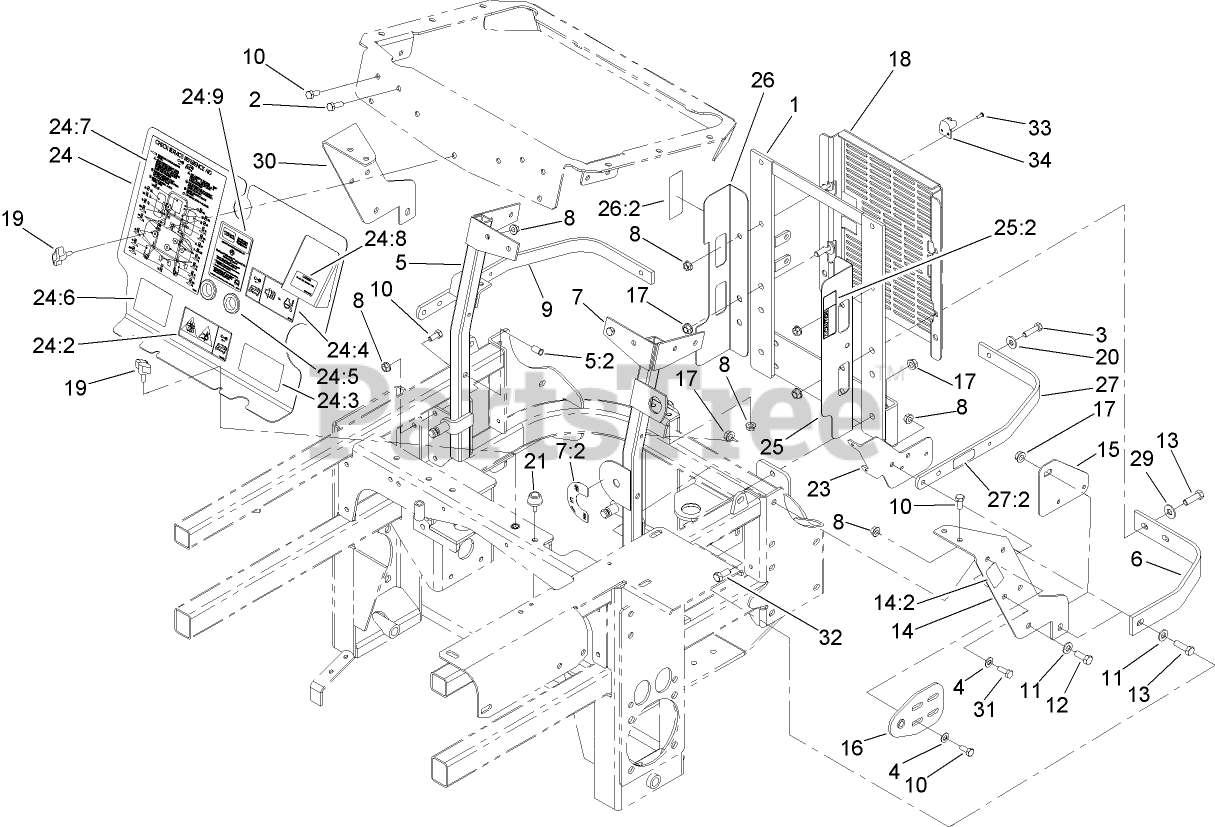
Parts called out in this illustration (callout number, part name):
1	SUPPORT-RADIATOR, REAR
2	SCREW-HH
3	SCREW-HH
4	WASHER-PLAIN
5	RH RADIATOR BRACE ASM
5:2	INSERT-THREADED
6	STRAP-GUARD
7	LH RADIATOR BRACE ASM
7:2	DECAL-VALVE, FUEL
8	NUT-HF
10	SCREW-HH
11	WASHER-FLAT
12	SCREW-HH
13	SCREW-HH
14	LH SUPPORT BRACKET ASM
14:2	DECAL-FUSES
15	BRACKET-PUMP, FUEL
16	PLATE-PIVOT, HOOD
17	NUT-HHF, WHIZ
18	SHIELD-COOLER
20	WASHER-FLAT
21	BUMPER-RUBBER
23	BRACKET-RELAY/FUSE
24	FRONT ENGINE SHIELD ASM
24:2	DECAL-DANGER, ROTATING DEVICES
24:3	DECAL-ROUTING, HYDRO BELT
24:4	DECAL- WARNING, BUZZER
24:5	GROMMET-RUBBER
24:6	DECAL-ROUTING, CLUTCH BELT
24:7	DECAL-CHECK, SERVICE
24:8	DECAL-CAUTION
24:9	DECAL-COOLANT
25	LH FAN GUARD ASM
25:2	DECAL-FAN, RADIATOR
26	RH FAN GUARD ASM
26:2	DECAL-FAN, RADIATOR
27	STRAP-TOP
27:2	DECAL-RELAY
29	WASHER-FLAT
30	BRACKET-SUPPORT, RH
31	SCREW-HH
32	SCREW-HH
33	RIVET
34	KEEPER-LATCH, RUBBER
